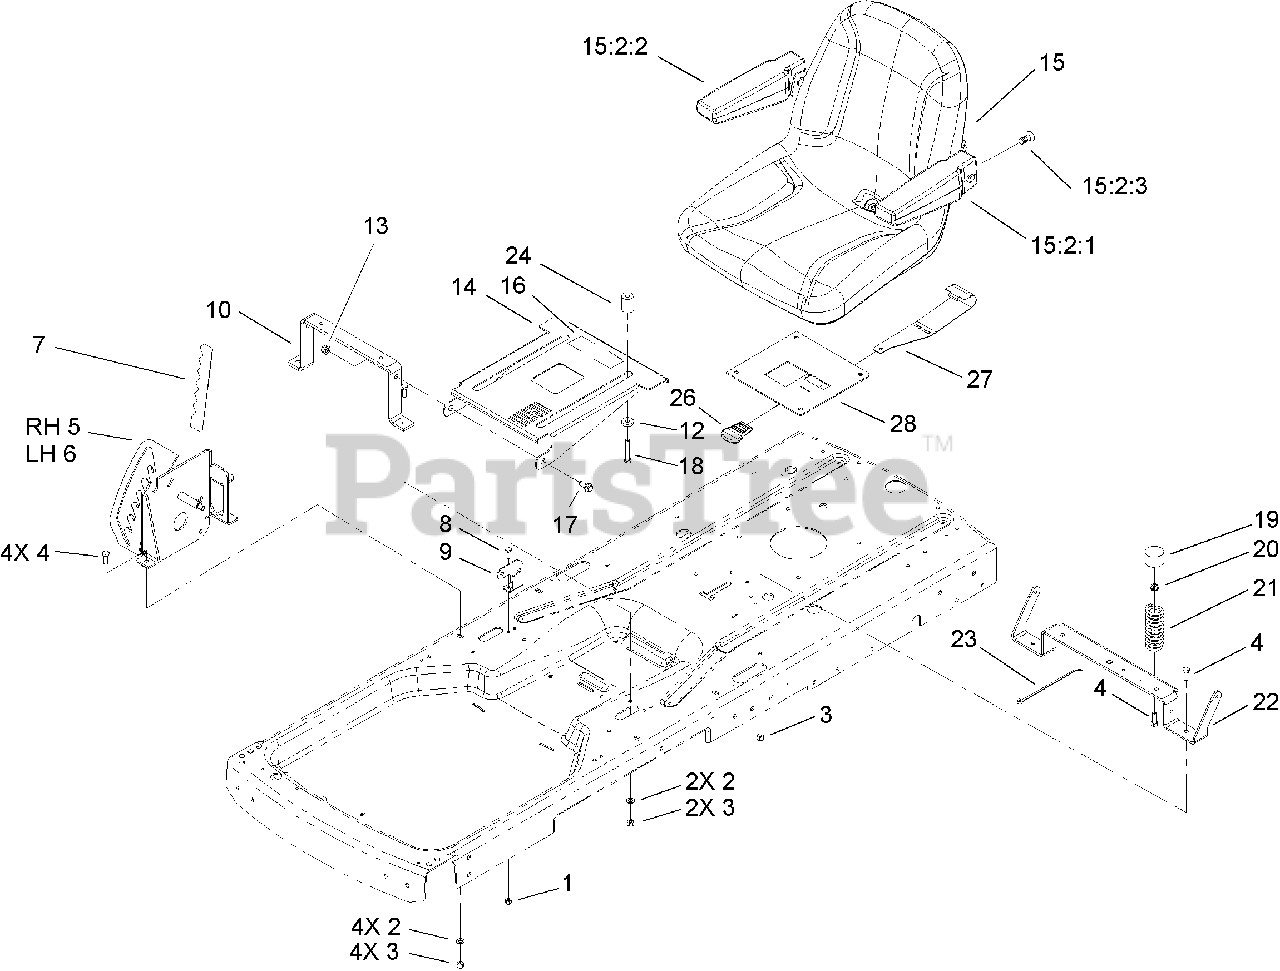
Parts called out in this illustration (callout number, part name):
1	NUT-LOCK, NI
2	WASHER-FLAT
3	NUT-LOCK, NI
4	SCREW-HH
5	RH PLATE ASM
6	LH PLATE ASM
7	DECAL-HOC
8	SCREW-HH
9	BRACKET-BELLCRANK
10	BRACE-SEAT, FRONT
14	BRACKET-SEAT
15	SEAT ASM
15:2:1	LH ARMREST ASM
15:2:2	RH ARMREST ASM
15:2:3	SCREW-HSBH
16	DECAL-SERVICES
17	BOLT-SHOULDER
18	SCREW-HH
19	CAP-PROTECTOR
21	SPRING-COMPRESSION
22	BRACE-SEAT, REAR
23	STRAP-TIE
26	KNOB-LEVER, HOC
27	LATCH-SEAT
28	MOUNT-LATCH, SEAT
